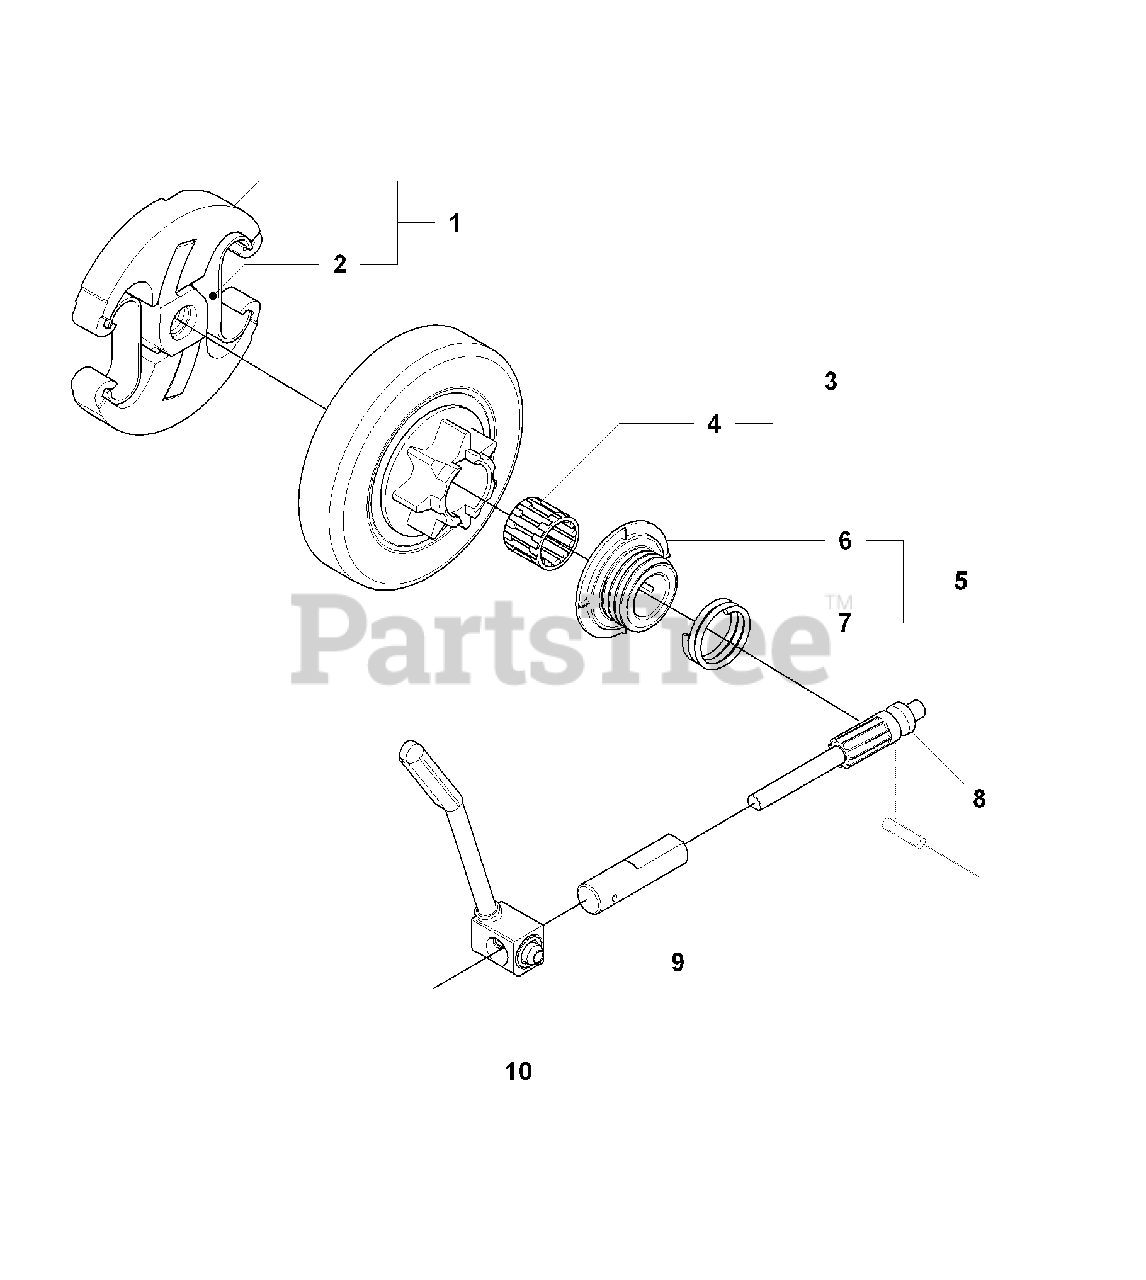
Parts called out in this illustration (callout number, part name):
3	CLUTCH DRUM
4	NEEDLE BEARING
5	GEAR WHEEL OIL PUMP
8	%PUMP PISTON
9	PUMP CYLINDER
